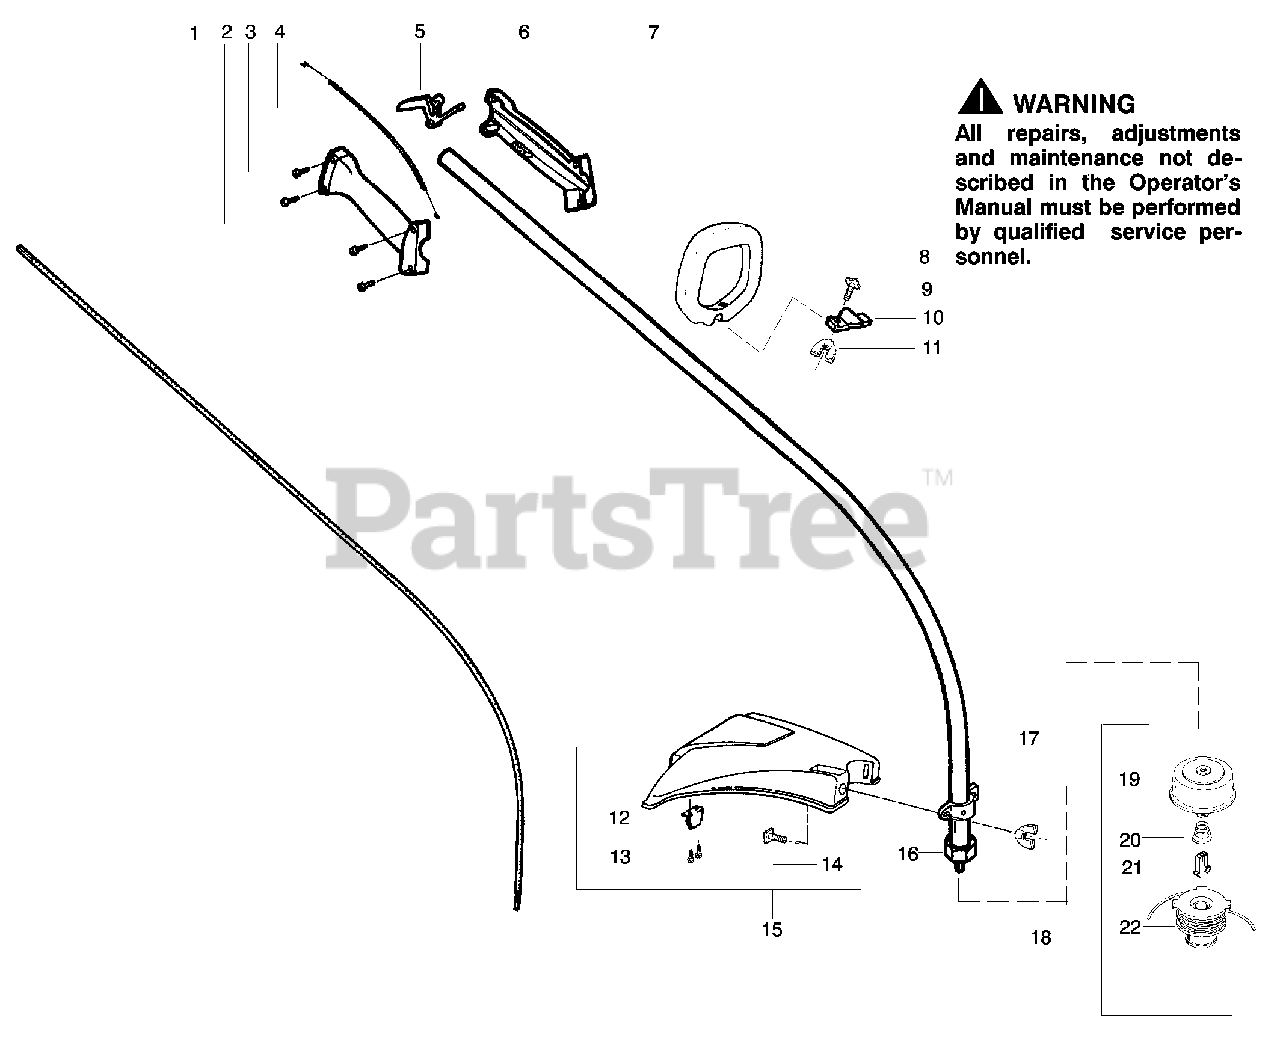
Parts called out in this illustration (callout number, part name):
1	Shaft-Flex
2	Throttle Hsg. (Right)
3	Screw-Throttle Hsg.
4	Assy-Throttle Cable
6	Throttle Hsg. (Left)
7	Assy-Drive Shaft Hsg.
8	Handle-Assist
9	Bolt-Handle/Shield
10	Clamp-Handle
11	Wingnut-Handle/Shield
12	Line Limiter
13	Screw-Line Limiter
14	Bolt-Handle/Shield
15	Kit-Shield Assy
16	Dust Cup
17	Wingnut-Handle/Shield
18	Accy-TNG VI Cutting Head
19	Assy-Hub
20	Spring-Compression
21	Clip-Retainer- Head
22	Accy-Spool w/Line
